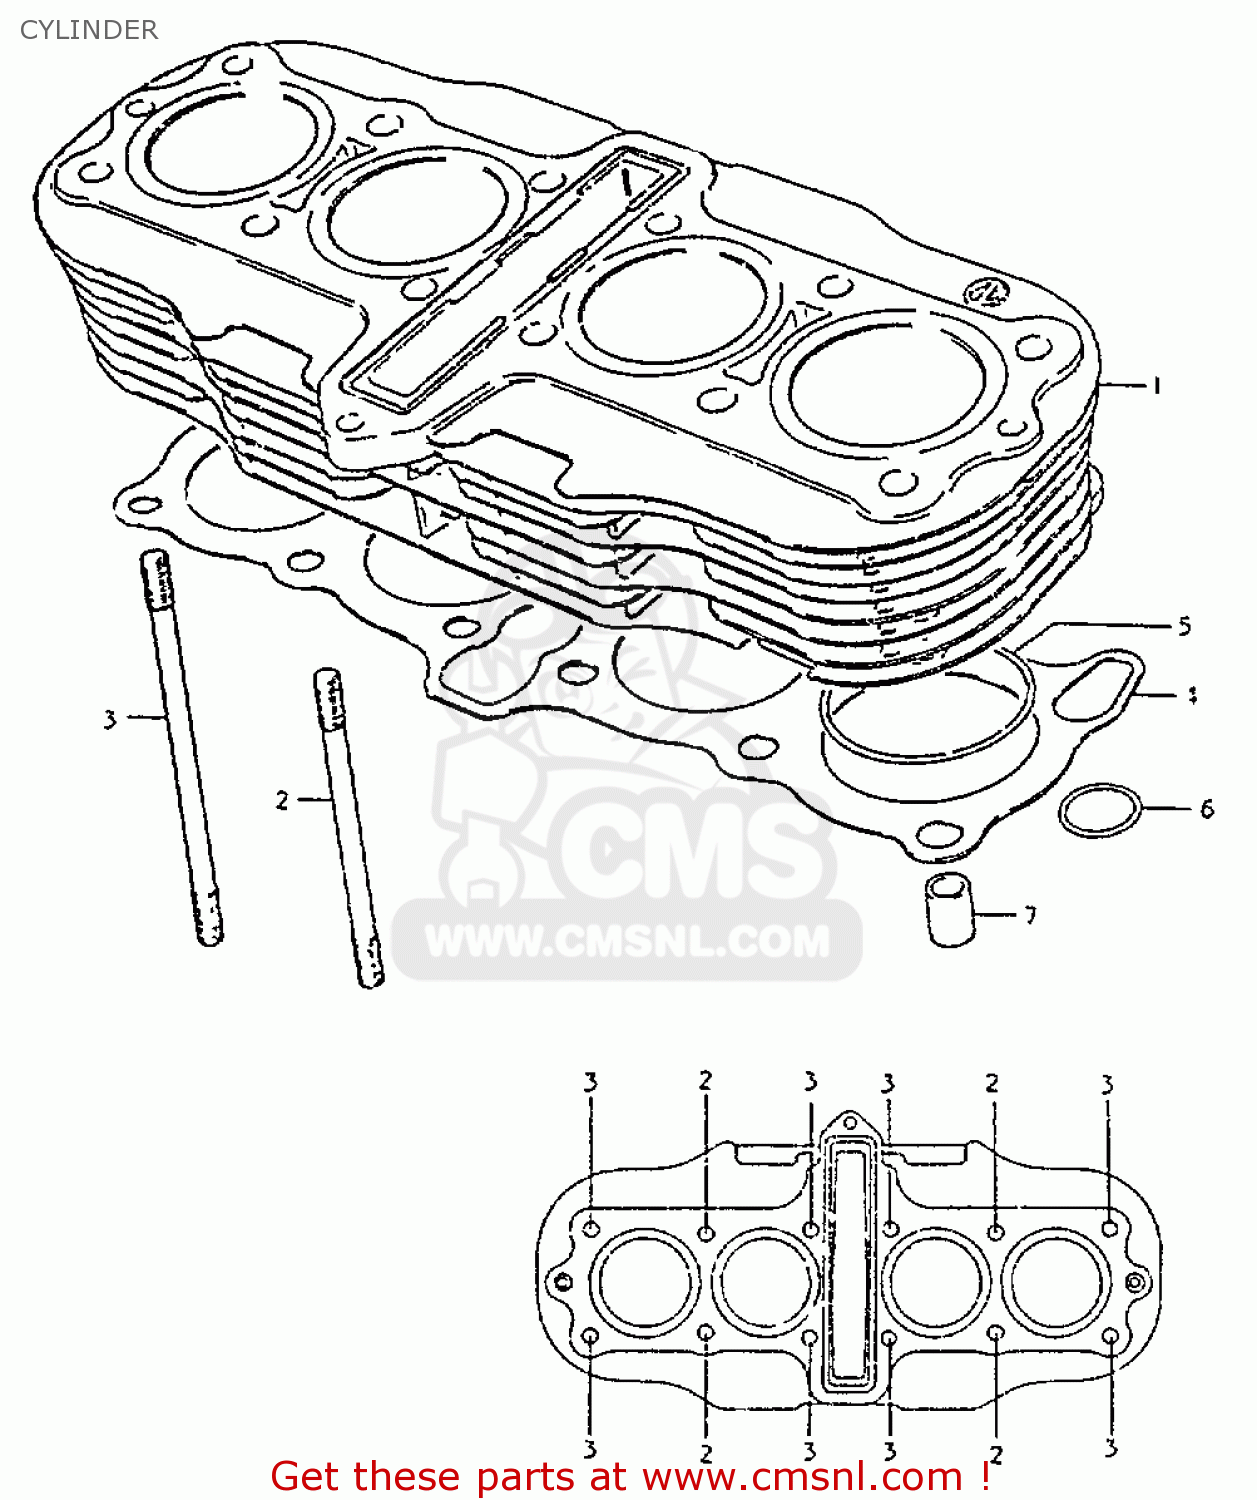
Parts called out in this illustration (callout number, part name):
1	CYLINDER
2	BOLT,STUD
3	BOLT,STUD
4	GASKET,CYLINDER (MCA)
5	O RING(D:2,ID:61)
6	INVALID PARTNUMBER
7	PIN
